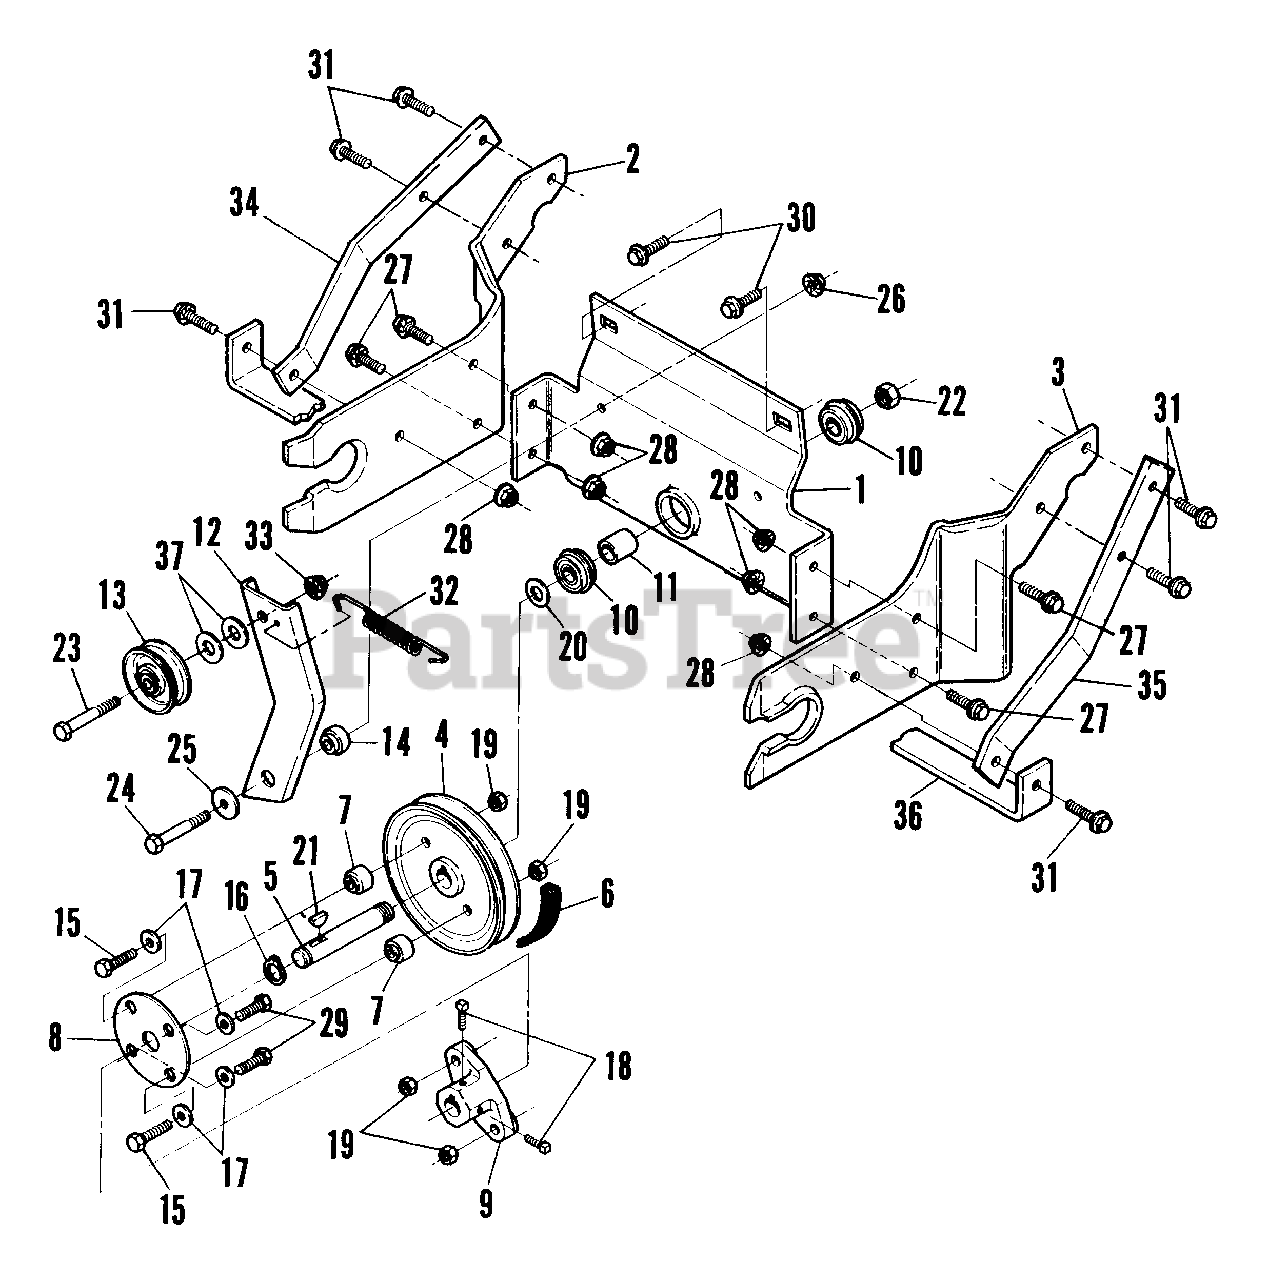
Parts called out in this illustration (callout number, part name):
1	WELDMENT, Hitch & Bearing
2	HITCH, Right Hand
3	HITCH, Left Hand
4	PULLEY, 5.25" O.D.
5	SHAFT, Pulley
6	BELT, Eng./Head 42.5
7	SPACER, Flex-Coupling .376 x .81 x .563
8	DISC, Flex-Coupling
9	HUB, Flex-Coupling
10	BEARING, Ball
11	SPACER, .62 x .88 x .91
12	ARM, Idler
13	IDLER, .250" O.D.
14	SPACER, Shoulder .33 x 1 x .151 Shld'r.
15	SCREW, 3/8 - 16 x 1 1/4" Hex Head Cap Gr. 5
16	RING, 5/8" External Retaining
17	WASHER, .406 x .75 x .132
18	SCREW, 5/16 - 18 x 1/2" Square Head Set
19	NUT, 3/8 - 16 Hex Lock
20	WASHER, Shim .62 x .81 x .016
21	KEY, (#6) 5/32 x 5/8" Woodruff
22	NUT, 5/8 - 18 Hex Lock
23	SCREW, 3/8 - 16 x 1 3/4" Hex Head Cap
24	SCREW, 5/16 - 18 x 1 1/4" Hex Head Cap
25	WASHER, 5/16" x 1-1/4" x 3/32" Flat
26	NUT, 5/16 - 18 Hex Flange Lock
27	BOLT, 3/8 - 16 x 1" Hex Flange Lock
28	NUT, 3/8 - 16 Hex Flange Lock
29	SCREW, 3/8 - 16 x 1" Hex Head Cap Gr. 5
30	BOLT, 3/8 - 16 x 3/4 Hex Flange Lock
31	BOLT, 3/8 - 16 x 1 1/4" Hex Flange Lock
32	SPRING, Idler 4"
33	NUT, 3/8 - 16 Hex Flange Lock
34	STIFFENER, R.H.
35	STIFFENER, L.H.
36	STIFFENER, Lower
37	WASHER, .406 x .812 x .080
